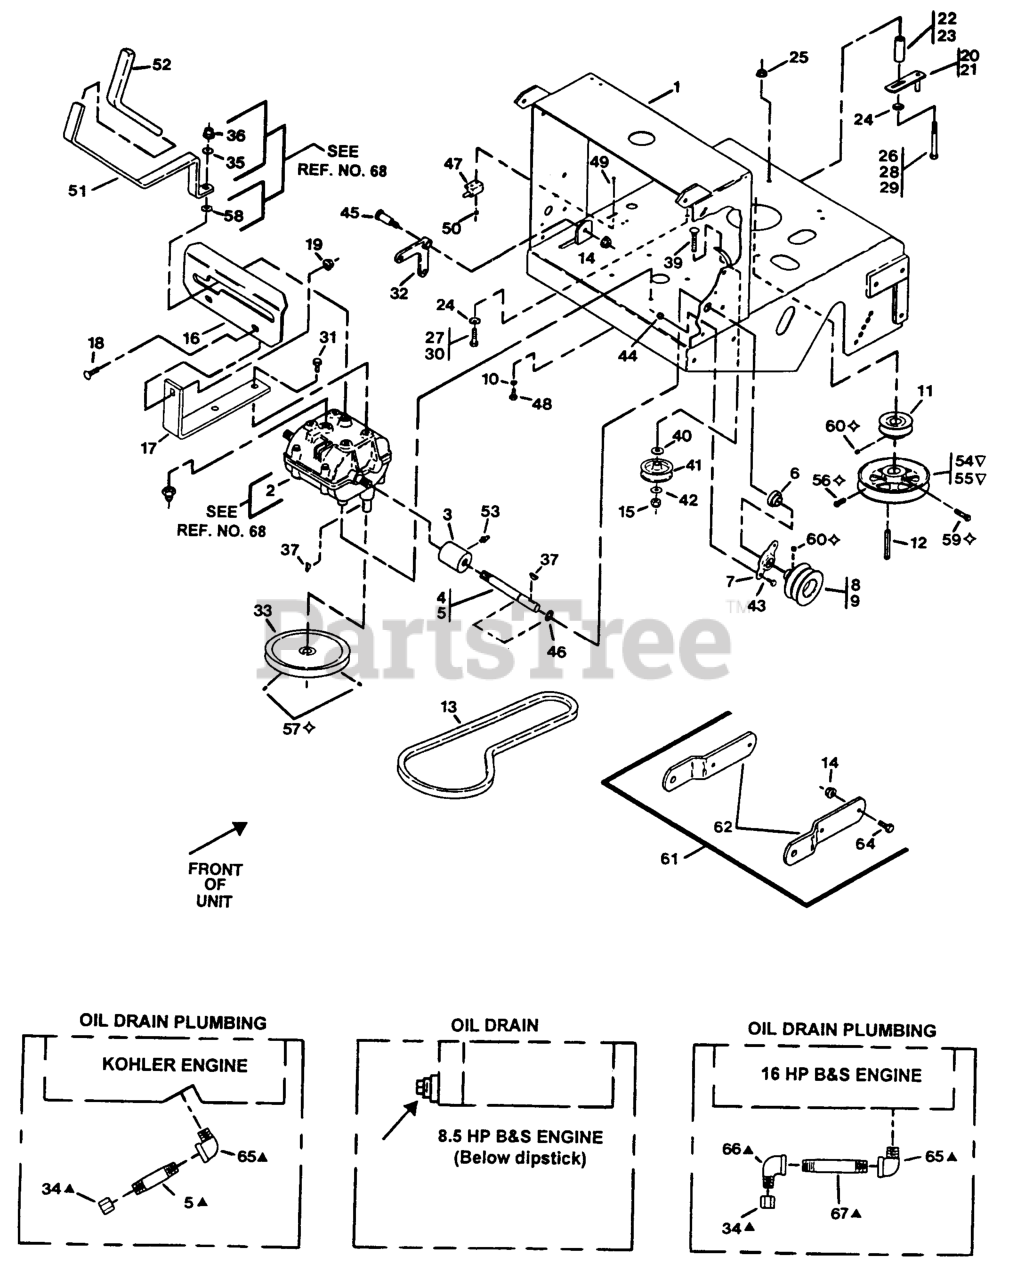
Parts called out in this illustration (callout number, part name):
5	NIPPLE
6	BEARING-SHAFT
7	FLANGE-OUTPUT
10	WASHER-LOCK
11	SHEAVE-TRANSMISSION
12	KEY,MACH 1/4X1/4X2-5/8
13	BELT,TRANS DRIVE
17	BRACKET-PLATE, SHIFT
20	GUIDE-BELT
21	GUIDE-BELT
24	WASHER-SPRING
28	SCRW,CAP HH M8X1.25X75M
29	SCRW,CAP HH M8X1.25X75M
32	BELLCRANK
33	SHEAVE-TRANSMISSION
34	CAP-HEX
38	SWITCH-START, NEUTRAL
45	BOLT-SHOULDER
47	SWITCH-OPEN, NORMALLY
54	SHEAVE,BLADE DRIVE
56	SCREW-SET
60	SCREW-SET
61	Metro Kit, Hitch Sulky
62	HITCH-SULKY
65	FITTING-ELBOW-90
66	ELBOW-90 DEG
67	NIPPLE
